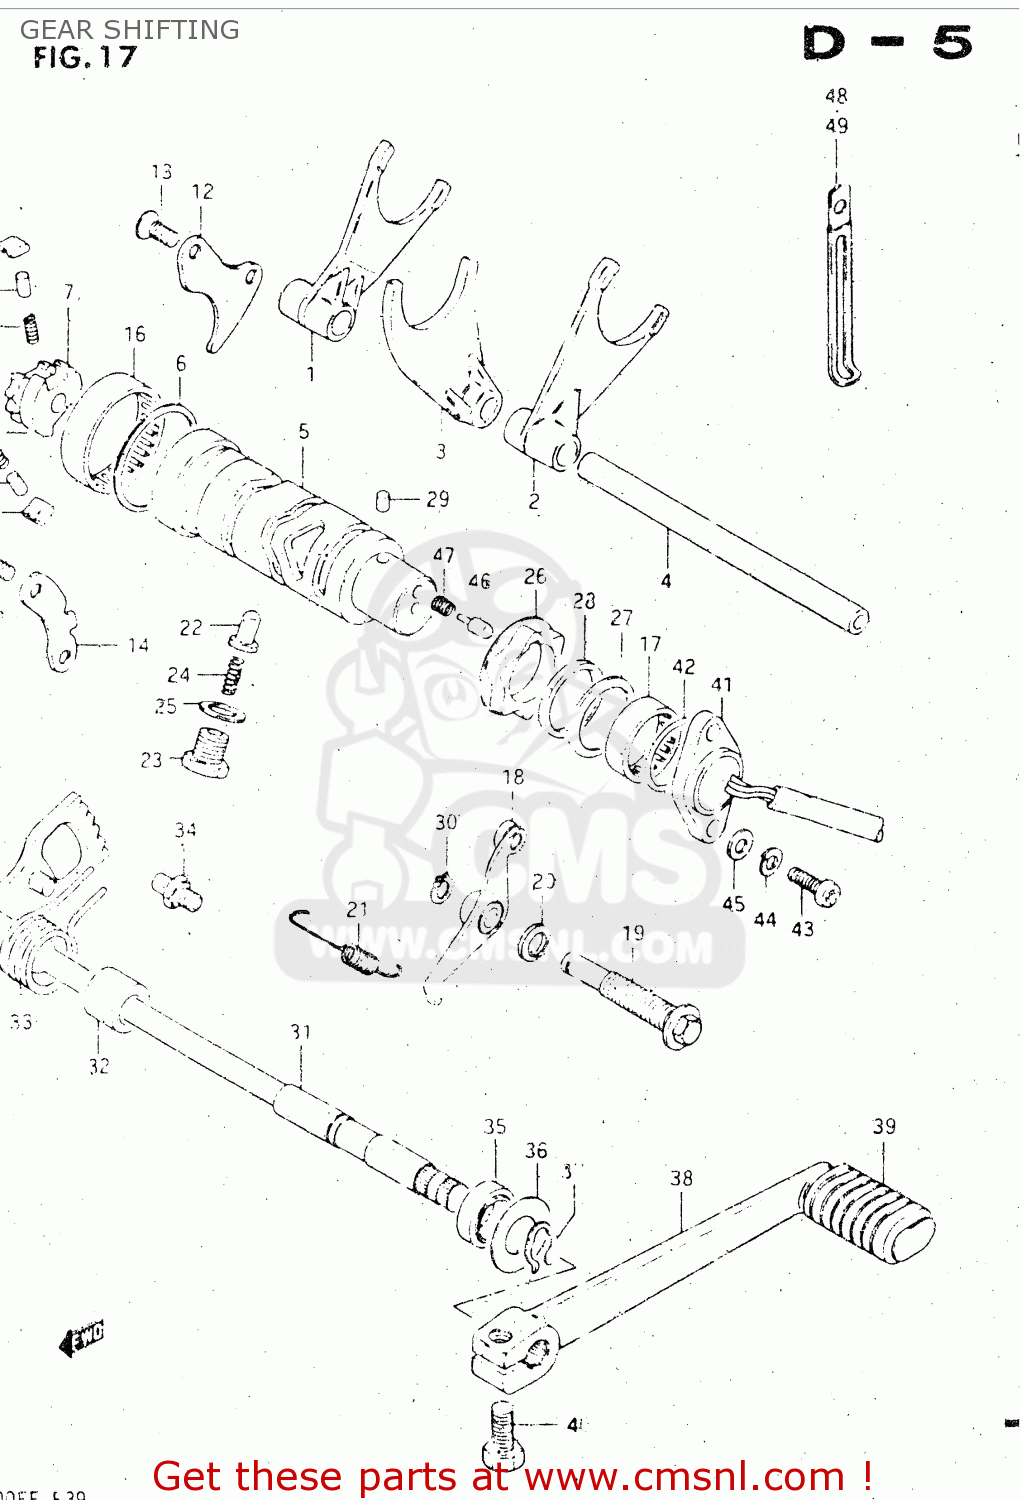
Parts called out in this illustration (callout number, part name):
1	FORK,GEAR SHIFT NO.1
2	FORK,GEAR SHIFT NO.2
3	FORK,GEAR SHIFT NO.3
4	SHAFT,GEAR SHIFT FORK
5	CAM,GEAR SHIFT
6	7
7	GEAR,GEARSHIFT CAM DRIVE
8	PAWL,GEAR SHIFT NO.1
9	PAWL,GEAR SHIFT NO.2
10	PIN(5X8)
11	SPRING
12	LIFTER,GEAR SHIFT PAWL
13	SCREW
14	GUIDE,GEAR SHIFT CAM
15	SCREW
16	BEARING(43X49X12)
17	BEARING(25X32X12)
18	STOPPER,GEAR SHIFTING
19	HOLDER,SHIFTING CAM STOPPER
20	GASKET(10X14X3.6) (NAS)
21	SPRING
22	STOPPER,GEAR SHIFTING
23	HOLDER,GEAR SHIFT CAM STOP SPR
24	SPRING
25	GASKET(14X19.2X2) (NAS)
26	PLATE,GEAR SHIFT CAM STOPPER
27	WASHER
28	WASHER
29	PIN 4X6
30	CIRCLIP
31	SHAFT,GEAR SHIFT
32	SPACER(12X20X15.3)
33	SPRING
34	STOPPER,GEAR SHIFT CAM
35	OIL SEAL
36	WASHER (12.5X27X1.6)
37	SPRING,RETAINER
38	LEVER ASSEMBLY,GEAR SHIFTING
39	RUBBER,PEDAL
40	BOLT
41	TERMINAL BASE ASSY,GEAR SHIFT
42	O-RING (D:2.4 ID:26.2)
43	SCREW(5X14)
44	LOCK WASHER
45	WASHER
46	PIN(5X15.5)
47	SPRING
48	CLAMP L:35
49	CLAMP
